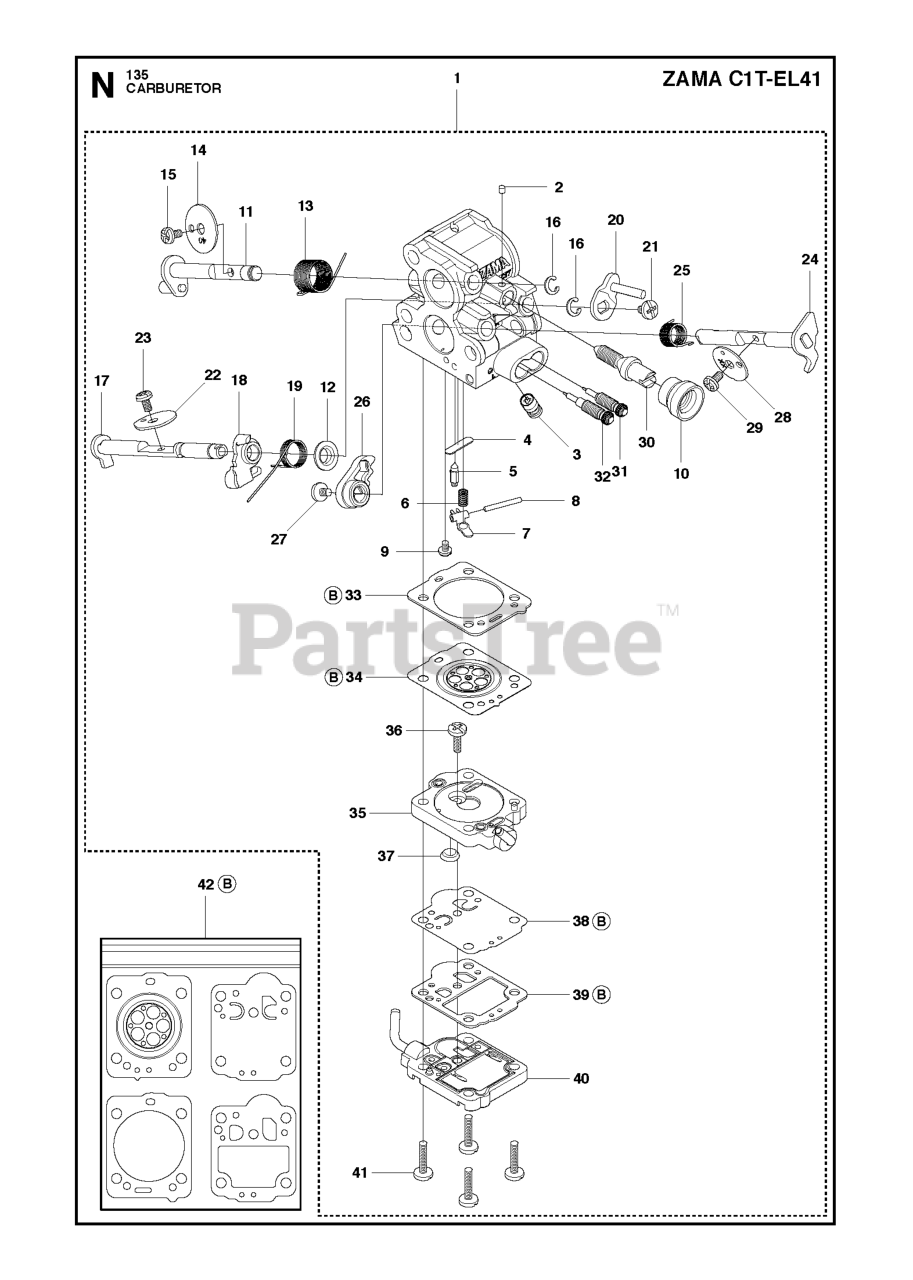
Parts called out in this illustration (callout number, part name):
1	CARBURETOR
2	PLUG
3	NOZZLE ASSY
4	PLUG
5	INLET NEEDLE
6	SPRING
7	LEVER
8	PIN RETAINING SCREW
9	SCREW
10	CAP ZAMA 0051034
11	SHAFT ASSY
12	COLLAR ZAMA 005020
13	SPRING
14	VALVE
15	SCREW
16	E RING
17	CHOKE SHAFT ASSY
18	LEVER
19	SPRING
20	LEVER
21	SCREW
22	VALVE
23	SCREW
24	THROTTLE SHAFT ASSY
25	SPRING
26	LEVER
27	SCREW
28	VALVE
29	SCREW
30	SCREW
31	SCREW
32	SCREW
33	GASKET
34	DIAPHRAGM
35	BODY
36	SCREW
37	STRAINER
38	DIAPHRAGM
39	GASKET
40	COVER
41	SCREW
42	GASKET KIT
